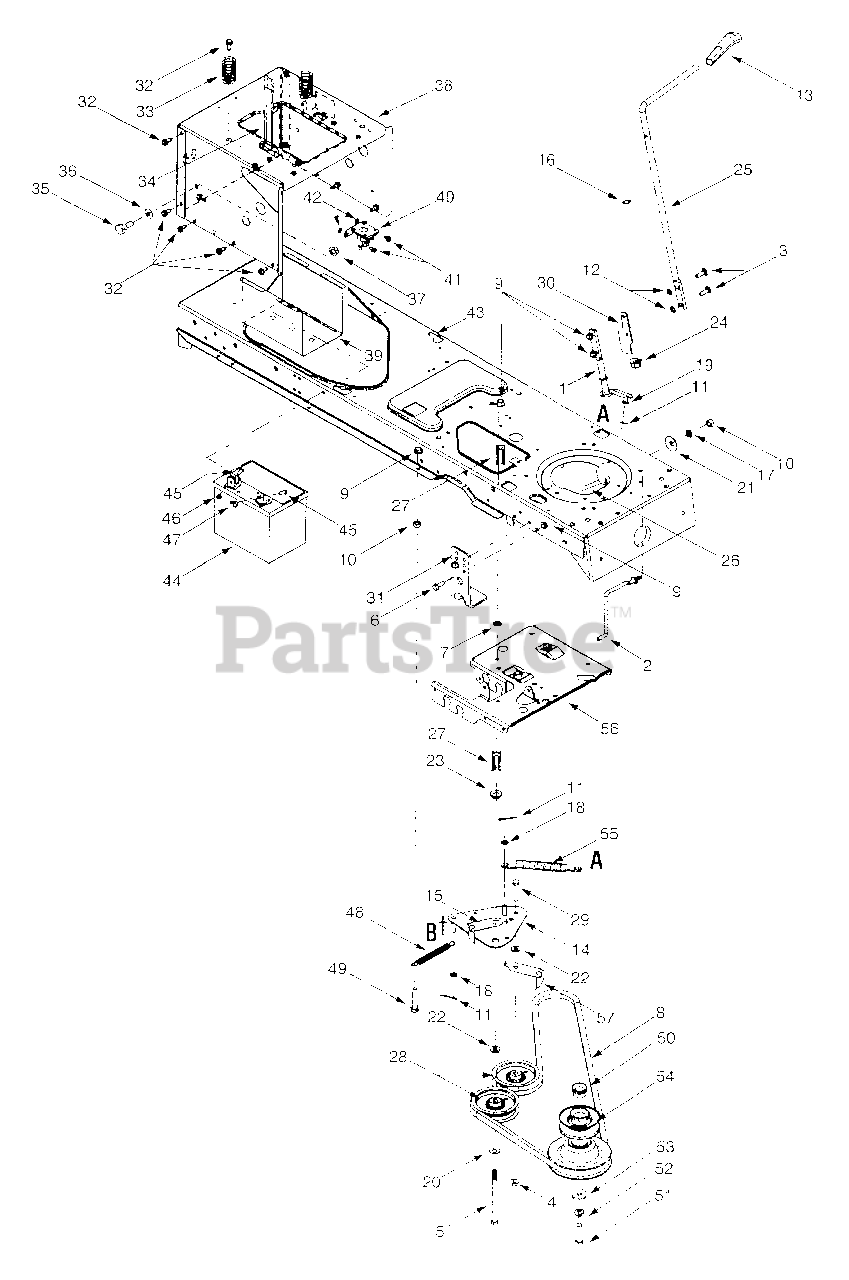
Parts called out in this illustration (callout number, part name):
1	PTO Engage Lever Assembly
2	Belt Keeper Rod
3	Carriage Screw, 5/16-18 x 1.00
4	Flange Lock Nut, 3/8-16
5	Hex Cap Screw, 3/8-16 x 5.5
6	Hex Head Washer Screw, 5/16-18 x .875
7	Push Nut, 3/8
8	PTO Belt
9	Flange Lock Nut, 5/16-18
10	Hex Nut, 5/16-18
11	Cotter Pin, 1/8 x 1.25
12	Speed Nut, .3125
13	PTO Knob
15	Belt Guard
16	Flat Washer, .510 x .750 x .033
17	Lock Washer, 5/16
18	Flat Washer, .385 x .62 x .063
19	Flat Washer, 5/16
20	Flat Washer, .406 x .875 x .059
21	Bell Washer, .39 x 1.13 x .062
22	Flat Washer, .407 x .812 x .135
23	Shoulder Spacer, .380
24	Hex Split Flange Bearing, .5
26	Belt Keeper Rod
27	Spacer, 3/8 x 1.54
28	Idler Pulley, 3.5
29	Hex Cap Screw, 3/8-16 x 1.75
32	Self Tapping Screw, 5/16-18 x .625
33	Compression Spring, 1.28 x 3.5
34	Battery Strap
35	Shoulder Screw, .625 x .5, 7/16-20
36	Bell Washer, .45 x 1.0 x .062
37	Flange Lock Nut, 7/16-20
41	Self Tapping Screw, 1/4-20 x.5
42	Lock Washer, 1/4
45	Hex Cap Screw, 1/4-20 x .62
46	Hex Sems Nut, 1/4-20
47	Wing Nut, 1/4-20
48	Extension Spring, .50 x 5.0
49	Hex Cap Screw, 5/16-18 x 1.75
50	Spacer Cup
51	Hex Head Cap Screw, 7/16-20 x 1.25
52	Lock Washer, 7/16
53	Flat Washer, .450 x 1.25
54	Engine Pulley, 3.56 OD x 5.56
55	Extension Spring, .75 x 6.75
57	Belt Guard
